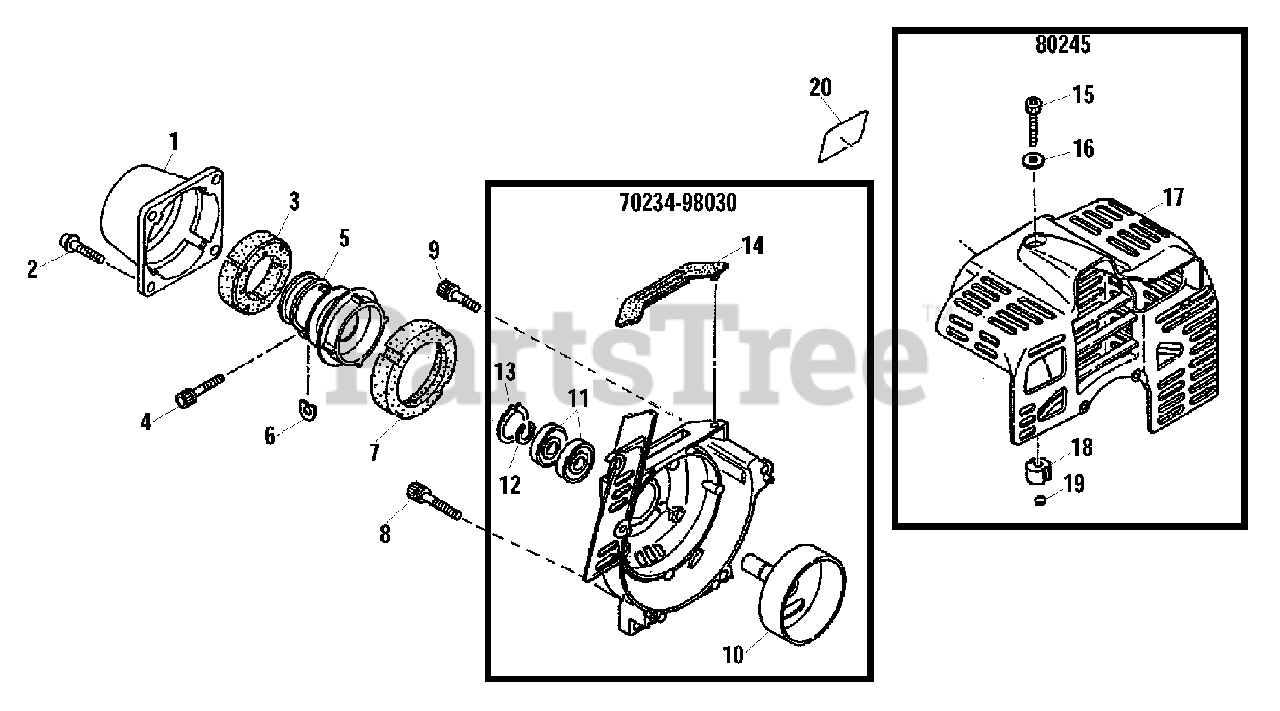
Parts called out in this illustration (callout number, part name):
1	CAP
2	SCREW - 5X16
3	CUSHION - FRONT
4	SCREW - 5X25
5	CLAMP, MAIN PIPE
6	SHIM
7	CUSHION - REAR
8	SCREW - 5X35
9	SCREW - 5X16
10	DRUM, CLUTCH
11	BEARING, BALL - 6000
12	RING, RETAINING
13	RING, RETAINING - 26
14	CUSHION
15	SCREW - 5X25
16	WASHER - 5
17	COVER, ENGINE - RED
18	INSULATOR
19	CLIP
20	LABEL - MODEL AH231
70234-98030	FAN CASE ASSY
80245	ENGINE COVER KIT - RED
